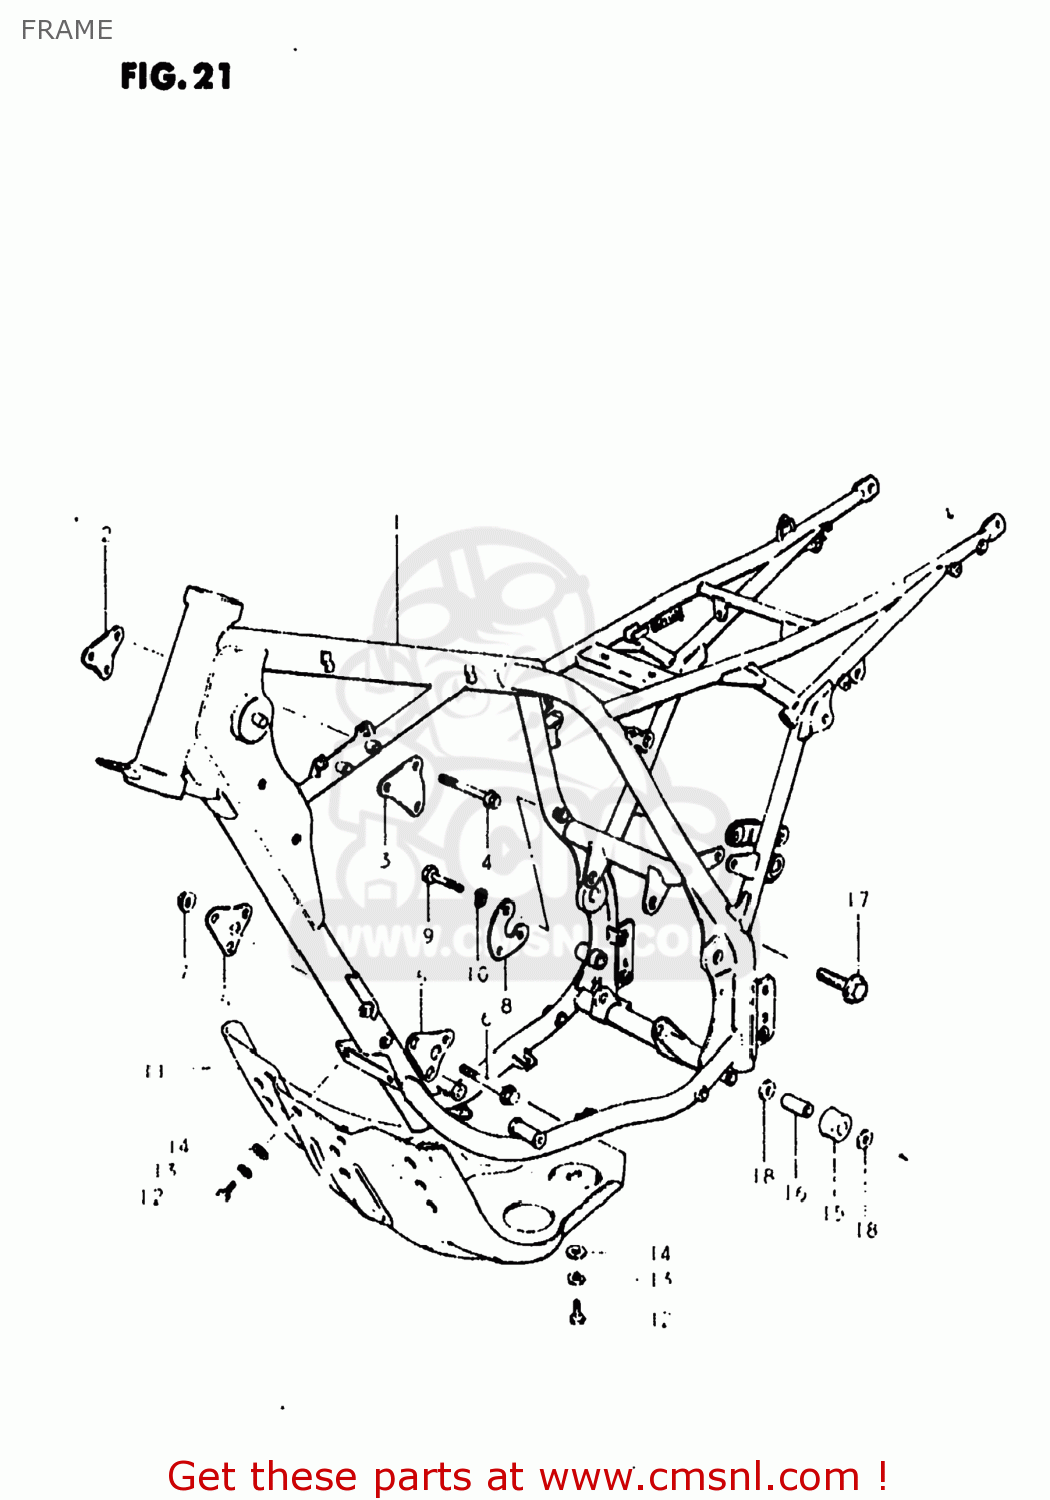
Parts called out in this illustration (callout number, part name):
1	FRAME
2	PLATE,ENGINE MOUNTING
3	PLATE,ENGINE MOUNTING
4	BOLT,UNDER
5	PLATE,ENGINE MOUNTING
6	BOLT(8X67)
7	NUT
8	PLATE,ENGINE MOUNTING
9	BOLT 8X55
10	LOCK WASHER
11	PROTECTOR,ENGINE
12	BOLT, UPPER
13	LOCK WASHER
14	WASHER 6MM
15	ROLLER,CHAIN CONTROL
16	SPACER,CHAIN LENGTH ROLLER
17	BOLT(8X45)
18	WASHER
